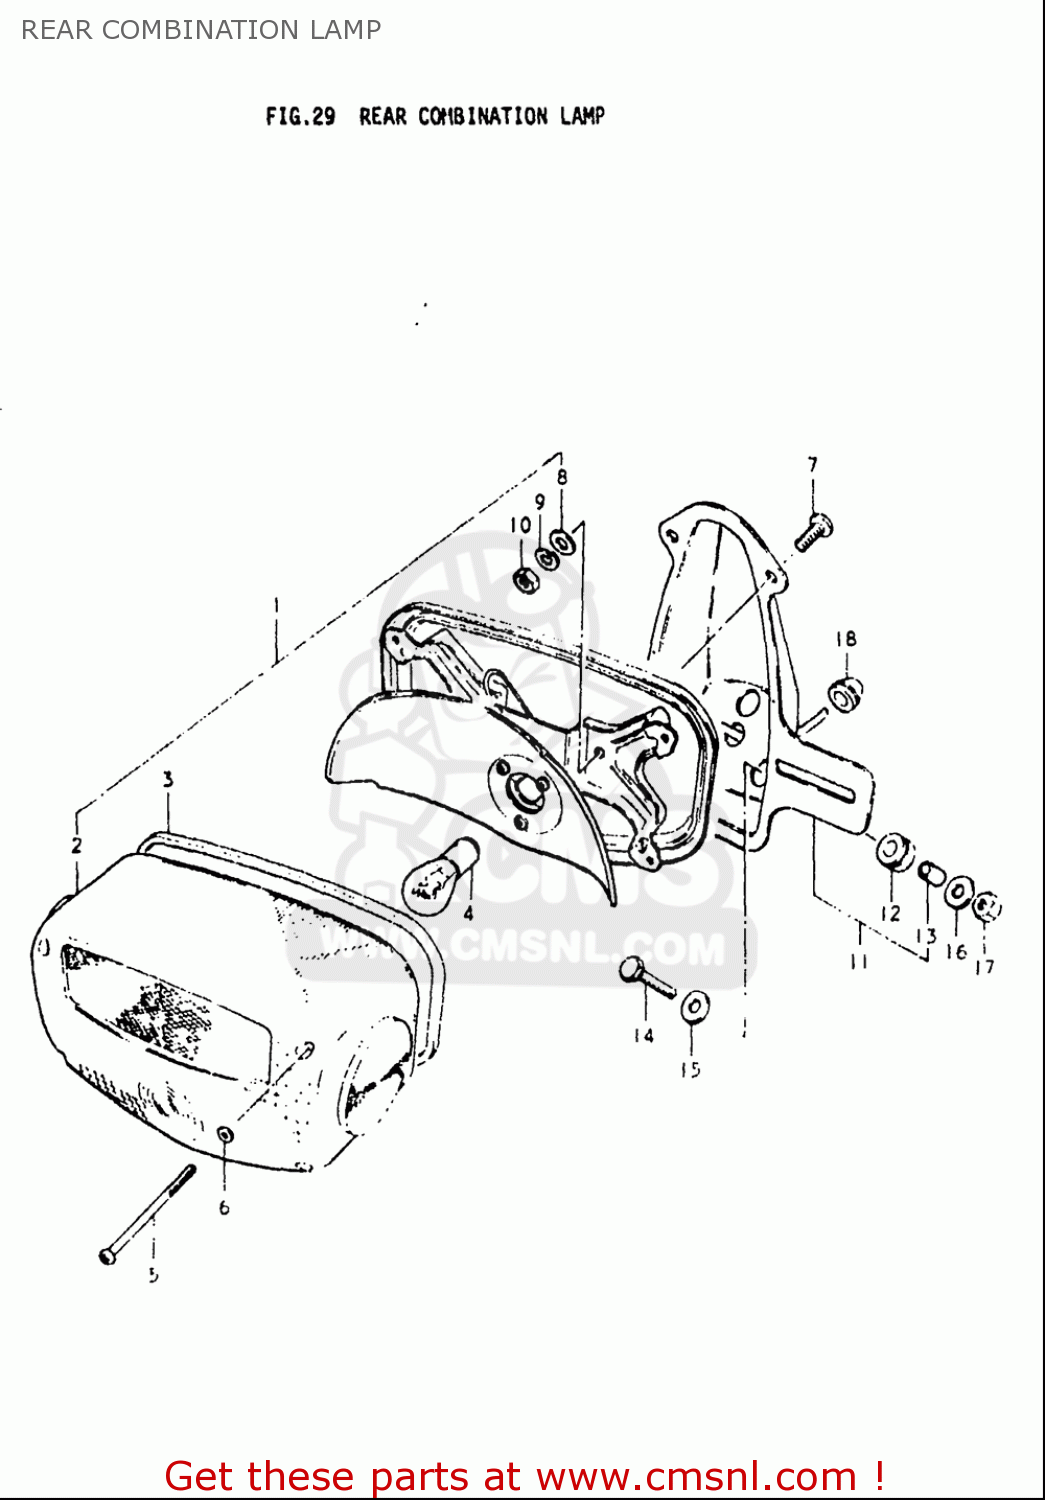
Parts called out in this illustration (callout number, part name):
1	LAMP UNIT,REAR COMBINATION
2	LENS
3	GASKET (NAS)
4	BULB(12V23W)
6	GASKET (NAS)
7	SCREW
8	WASHER
9	WASHER,LOCK
10	NUT
12	CUSHION
13	SPACER
14	BOLT
15	WASHER(6.5X20X1.2)
16	WASHER
17	NUT
18	GROMMET
